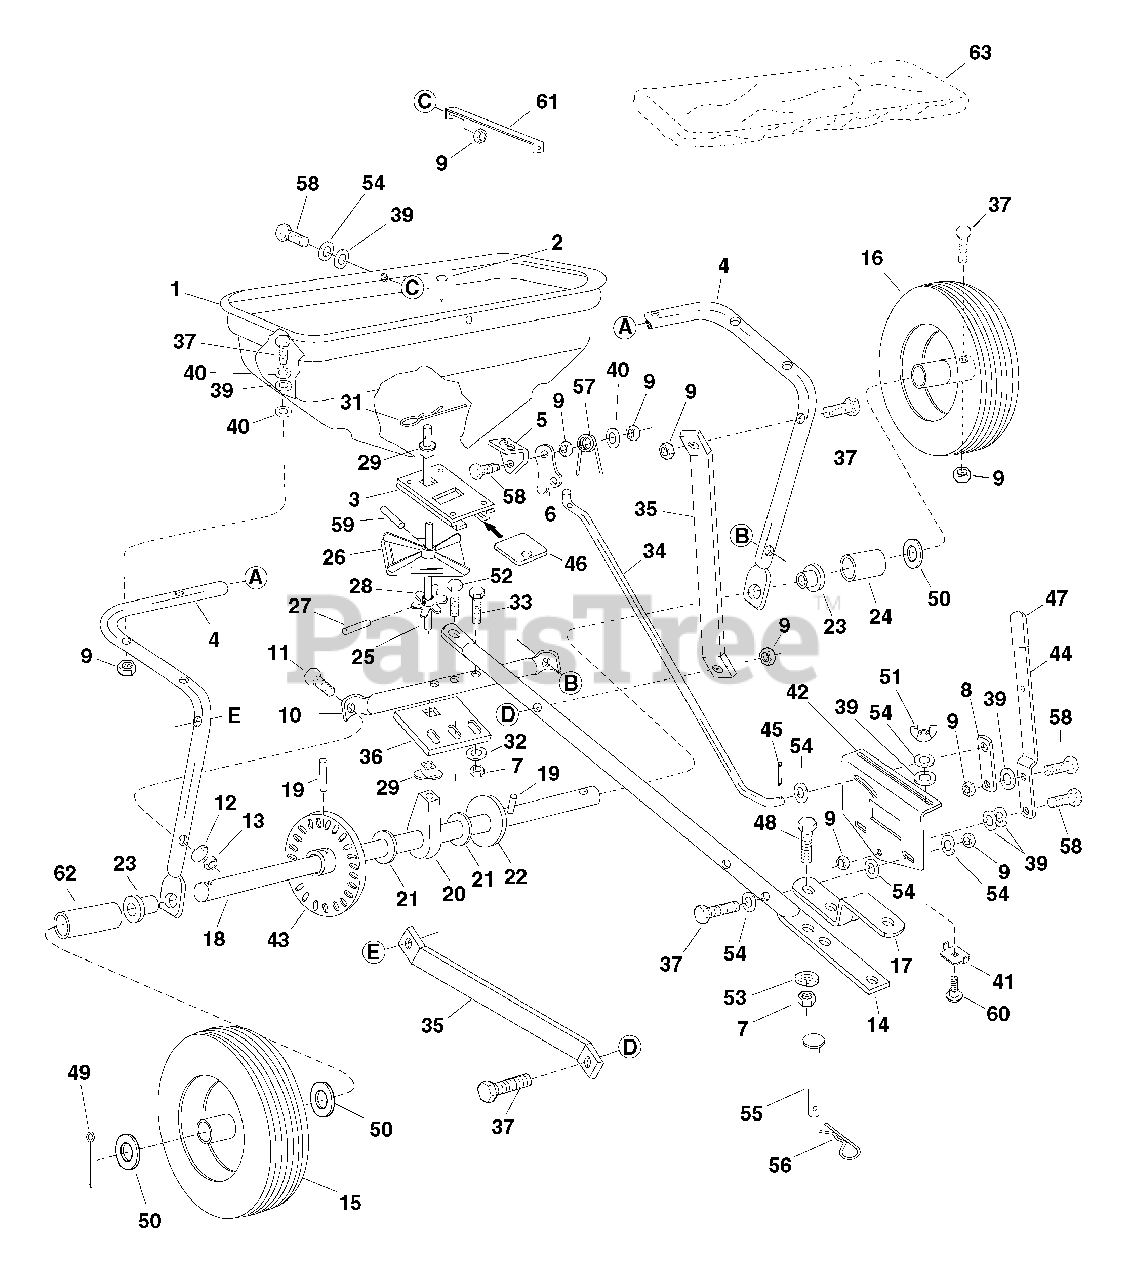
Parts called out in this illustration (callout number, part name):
2	Rivet, Stainless
3	Ass'y, Guide Closure
4	Tube, Frame
5	Slide Gate Angle Bracket
6	Slide Gate Bracket
7	Nut, Hex Lock 3/8-16 Thd.
8	Flow Control Link
9	Nut, Hex Lock 1/4-20 Thd.
10	Tube, Crossover
11	Bolt, Hex 5/16-18 x 1-3/4" Lg.
12	Lock Washer, 5/16"
13	Nut, Hex Lock, 5/16-18 Thd.
14	Tube, Hitch
15	Wheel, Idler
16	Wheel, Drive
17	Bracket, Hitch
18	Shaft, Axle
19	Pin, Spring 3/16" Dia. x 1-1/4" Lg.
20	Bushing, Axle Shaft
21	Washer, Flat .78 I.D.
22	Washer, Flat 1/2"
23	Bearing, Flange
24	Spacer Tube (Short)
25	Shaft, Sprocket
26	Spreader Plate
27	Pin, Spring 1/8" Dia. x 5/8".
28	Sprocket, 6 Tooth
29	Bushing, Delrin
31	Hairpin, Agitator
32	Washer, Flat 3/8".
33	Bolt, Hex 3/8-16 x 1-3/4" Lg.
34	Rod, Flow Control
35	Brace, Hitch
36	Shaft Support Plate
37	Bolt, Hex 1/4-20 x 1-3/4"
39	Washer, Nylon
40	Washer, Flat 1/4" Std.
41	Stop, Adjustable
42	Bracket, Flow Control Mount
43	Gear Assembly
44	Flow Control Arm
45	Cotter Pin 3/32" x 3/4" Lg.
46	Plate, Closure
47	Grip, Flow Control Arm
48	Bolt, Hex 3/8-16 x 1-1/4" Lg.
49	Pin, Cotter 1/8" x 1-1/2"
50	Washer, Flat 1-5/8" O.D.
51	Wing Nut, Nylon
52	Bolt, Hex 3/8-16 x 2" Lg.
53	Lock Washer, 3/8"
54	Washer, 5/16 SAE
55	Hitch Pin
56	Hair Cotter Pin, 1/8"
57	Spring, Torsion
58	Bolt, Hex 1/4-20 x 3/4" Lg.
59	Pin, Spring 1/8" Dia. x 1" Lg.
60	Bolt, Carriage 1/4-20 x 3/4"
61	Strap, Hopper
62	Spacer Tube (Long)
63	Vinyl Cover
